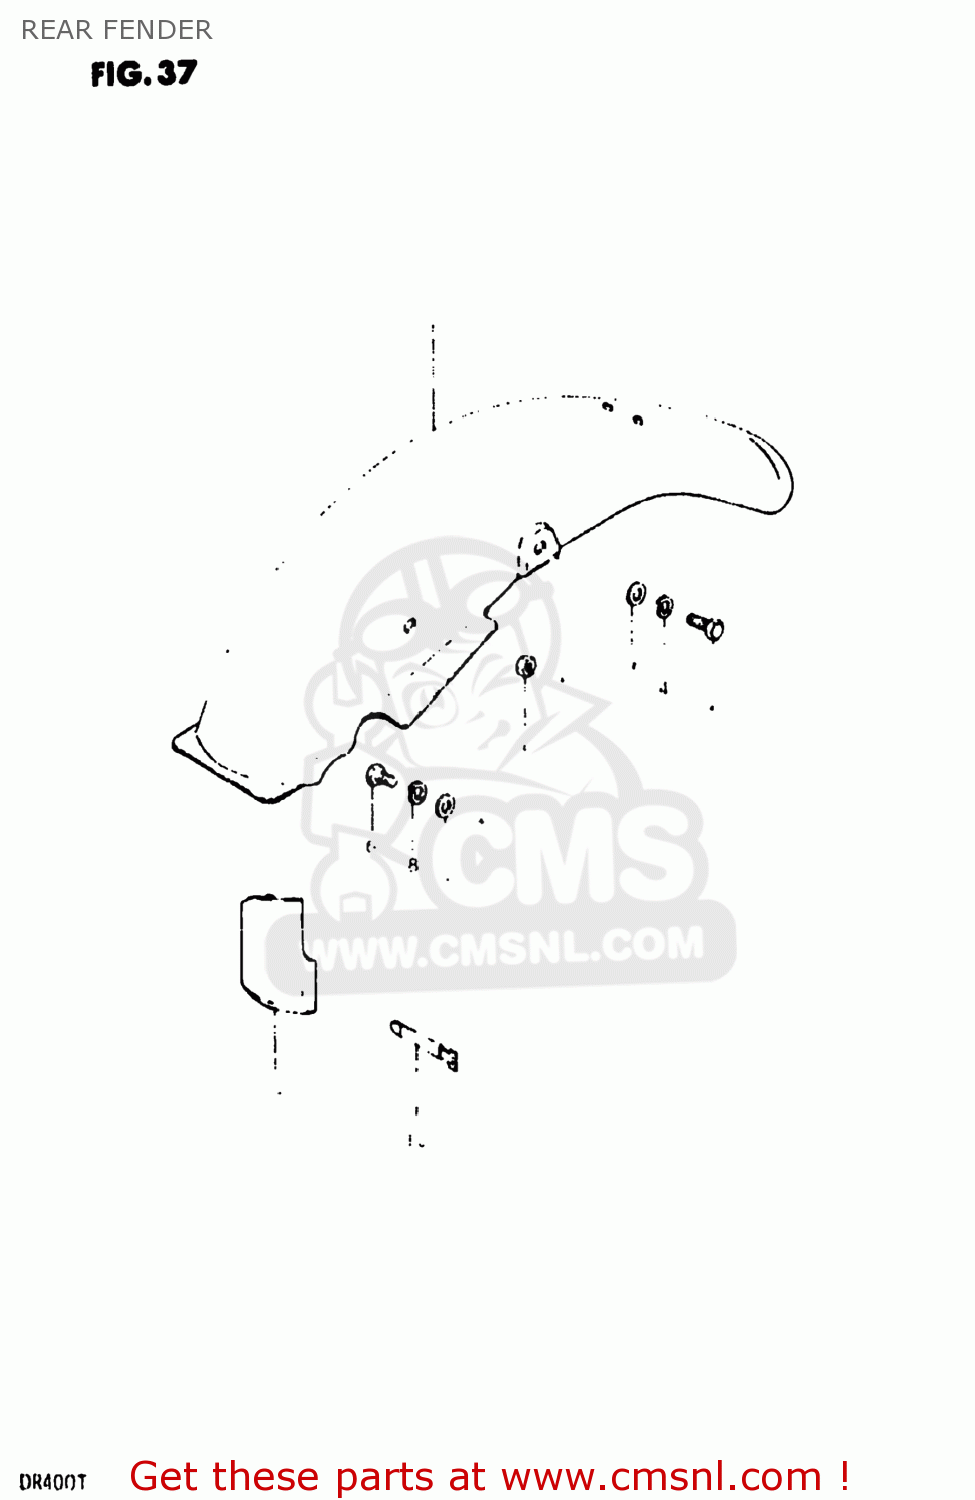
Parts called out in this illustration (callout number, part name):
1	FENDER,REAR
2	BOLT
3	WASHER (8.2X20X1.6)
4	WASHER,LOCK,8.
5	NUT
6	BOLT
7	WASHER (8.2X20X1.6)
8	LOCK WASHER
9	MUD GUARD,REAR FENDER
10	CLAMP L:110
